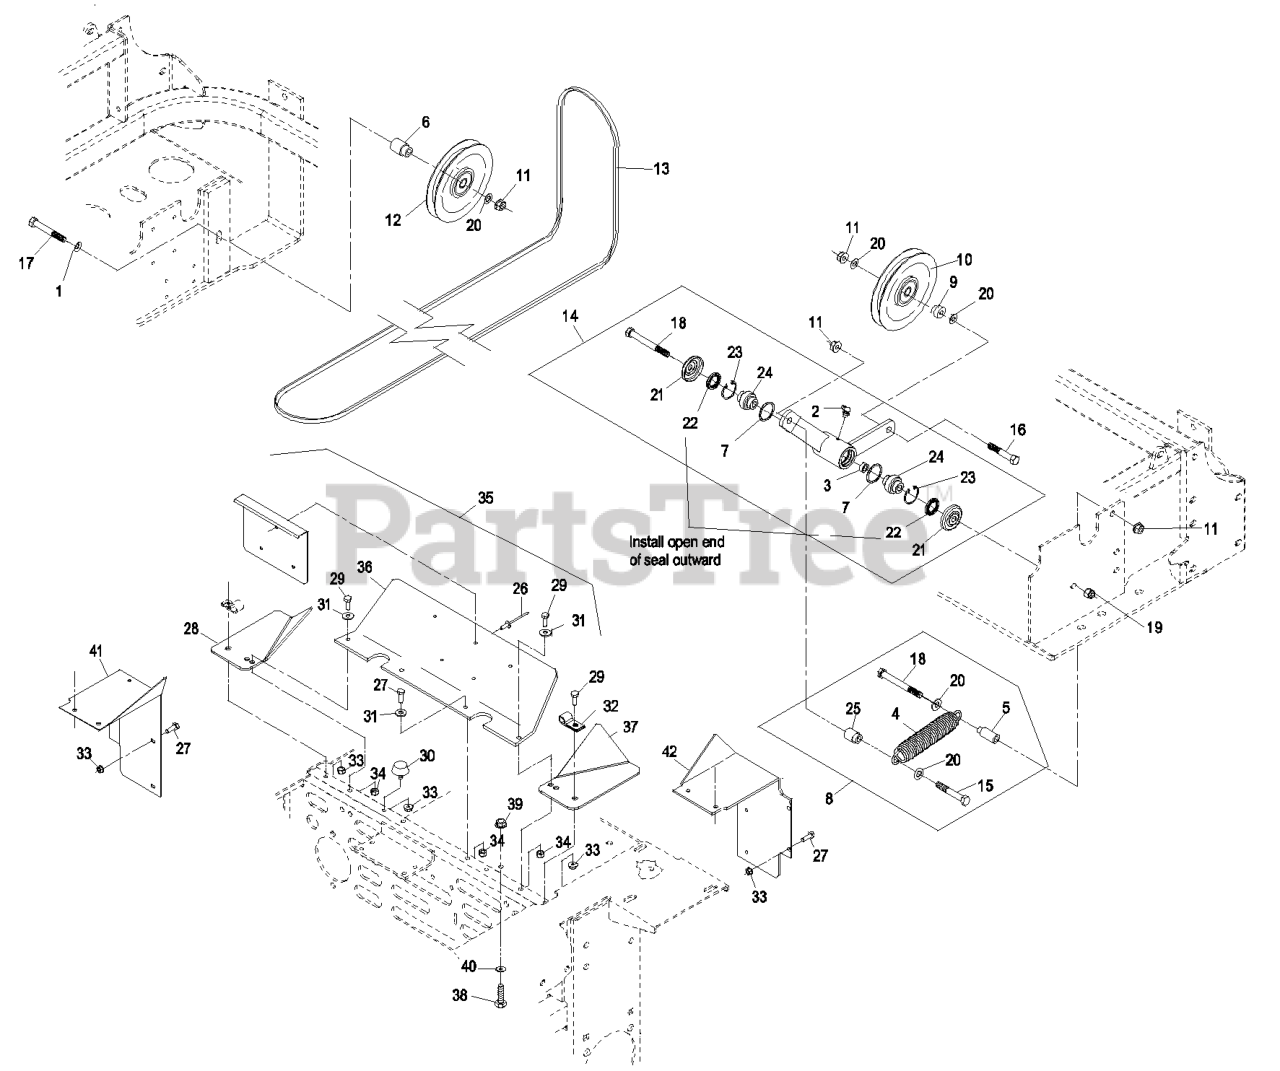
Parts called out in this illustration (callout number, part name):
1	WASHER-BELLEVILLE
2	FITTING-GREASE, 90 DEG
5	SPACER,SPRING MOUNT
6	BUSHING-IDLER
8	KIT,MULE DRIVE SPRING
9	BUSHING-IDLER
10	PULLEY-IDLER
11	NUT-HHF, WHIZ
12	PULLEY-IDLER
13	BELT,B 116.1"
14	KIT,MULE IDLER LZ
15	SCREW-HH
16	SCREW-HH
17	SCREW-HH
18	SCREW-HH
19	NUT-LOCK, NI
20	WASHER-FLAT
21	GUARD-TOP
22	SEAL-LIP, SINGLE
23	RING-SNAP
24	BEARING-SPHERICAL
25	BUSHING-IDLER
26	RIVET-POP
27	SCREW-HH
28	SUPPORT-FRONT COVER, RH
29	SCREW-HH
30	BUMPER-RUBBER
31	WASHER-FLAT
32	CLIP-LOOM
33	NUT-HF
34	NUT-LOCK, NI
35	SHIELD ASM
36	SHIELD-ENGINE
37	SUPPORT-FRONT COVER, LH
38	SCREW-HH
39	NUT-HHF, WHIZ
40	WASHER-BELLEVILLE
